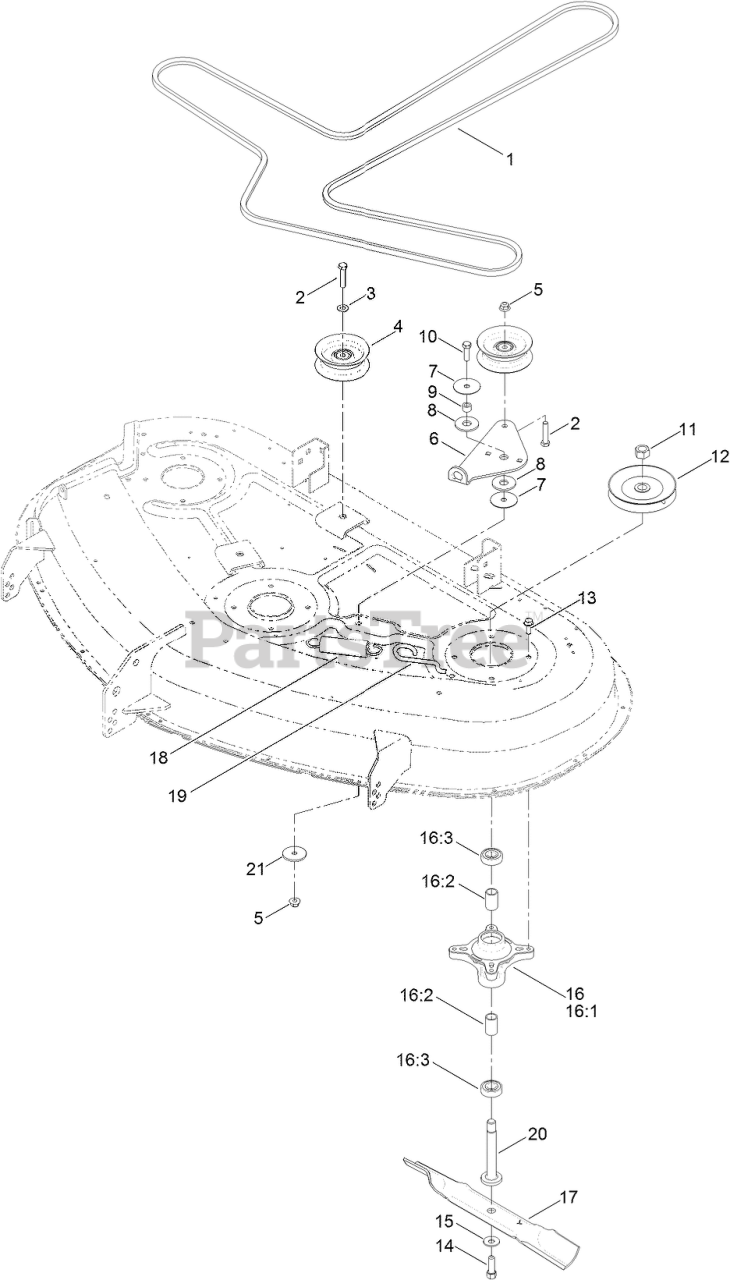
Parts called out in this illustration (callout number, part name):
1	V-BELT
2	SCREW-HH
3	WASHER-FLAT
4	PULLEY-IDLER, FLAT
5	NUT-HF, NI
6	ARM-IDLER
7	WASHER
8	WASHER-FRICTION, COMPOSITE
9	SPACER
10	SCREW-HH
11	NUT-HEX
12	PULLEY
13	SCREW-TAPTITE
14	SCREW-HH
15	WASHER-BELLEVILLE
16	SPINDLE ASM
16:1	SPINDLE
16:2	SPACER
16:3	BEARING-BALL
17	BLADE-HI LIFT
18	SPRING-EXTENSION
19	HOOK-RETURN, SPRING
20	SHAFT-SPINDLE
21	WASHER-REBOUND
